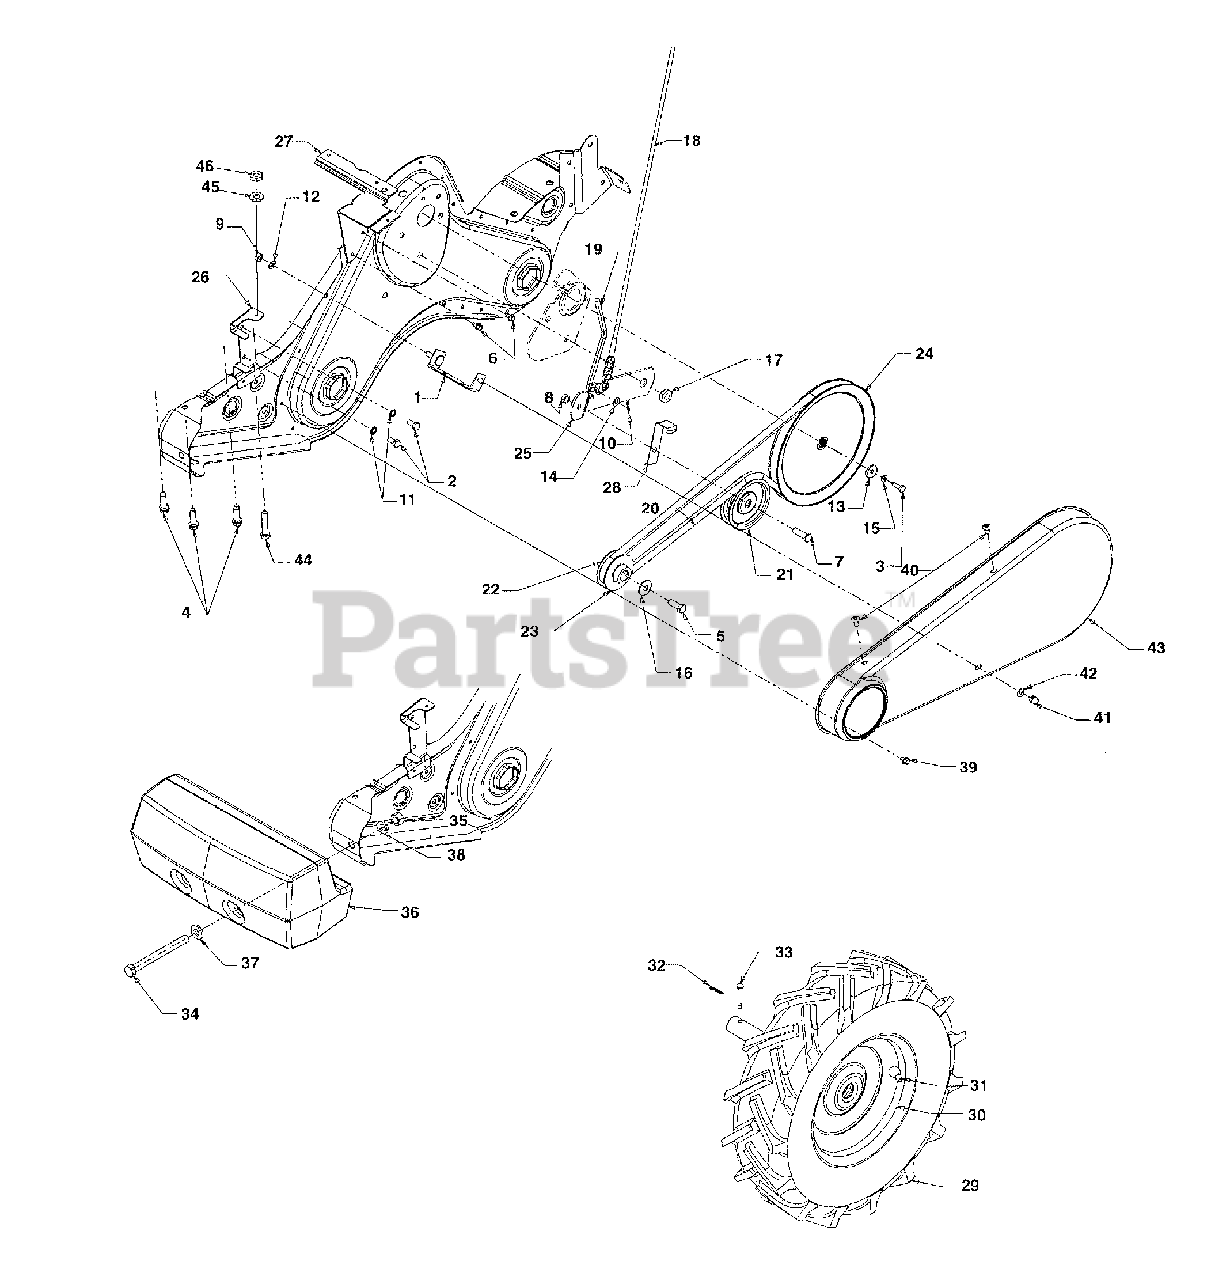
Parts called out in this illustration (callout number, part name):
2	Hex Bolt 5/16-24 x .62" Lg.
3	Hex Bolt 1/4-28 x .75" Lg.
4	Hex Wash. TT-Sems Screw 3/8-16 x 1.250" Lg.
5	Hex Bolt 3/8-24 x 1.00
6	Hex Wash. Hd. S-Tap Scr.
7	Hex Cap Screw 3/8-16 x 1.25
8	Ctr. Lock Jam Nut 3/8-16
9	Hex Nut 5/16-18
10	Internal Cotter Pin
11	Hairpin Clip
12	L-Wash. 5/16" I.D.
13	Fl-Wash. 1/4 I.D. x .93 O.D.
14	Spring-Wash .317 x .625 O.D. x .099
15	L-Wash. 1/4" I.D.
16	Bell-Wash. .396 x 1.140 x .095
17	Shld. Nut 7/16-20
18	Clutch Cable
19	Idler Pulley Rod
20	Belt: 4L x 58.16 Lg.
21	Fl-Idler w/Flange 3.75" O.D.
22	Outer Engine Pulley Half
23	Inner Engine Pulley Half
24	Input Pulley
25	Idler Bracket
32	Clevis Pin
33	Internal Cotter Pin
34	Hex Hd. Cap Screw 1/2-13 Gr. 5
35	Hex Nut 1/2-13 Thd. Gr. 5
36	Counterweight
37	Fl-Wash 510" I.D. x 1.0" O.D.
38	L-Wash. 1/2" Lg.
39	Hex Screw 1/4-20 x .375" Lg.
40	Screw 1/4-14 x .625" Lg.
41	Acorn Lock Nut
42	Fl-Washer 1/4 x .620" Lg.
44	Hex Bolt 5/16-18 x 1.50" Lg.
45	Bell-Wash 340 I.D. x .872 O.D.
46	Nut: Hex 5/16-18
